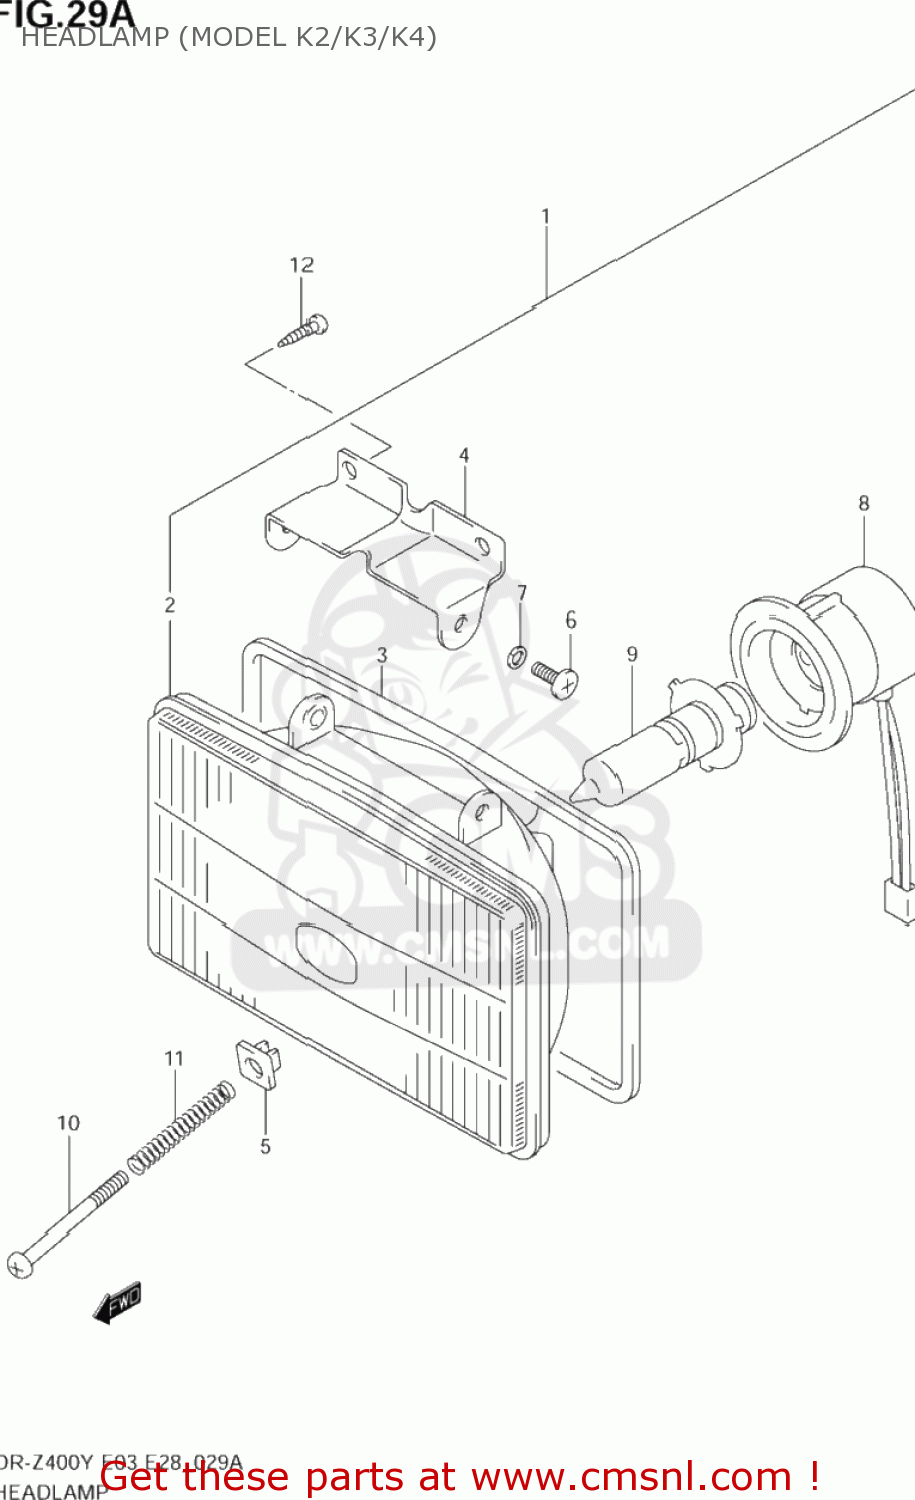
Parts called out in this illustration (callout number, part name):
1	HEADLAMP ASSY
2	UNIT,LAMP
3	GASKET,HEADLAMP (NAS)
4	BRACKET,LAMP
5	NUT,ADJUSTING
6	SCREW
7	WASHER,LOCK
8	SOCKET
9	BULB(12V35/36.5W)
10	SCREW(4X75)
11	SPRING
12	SCREW
